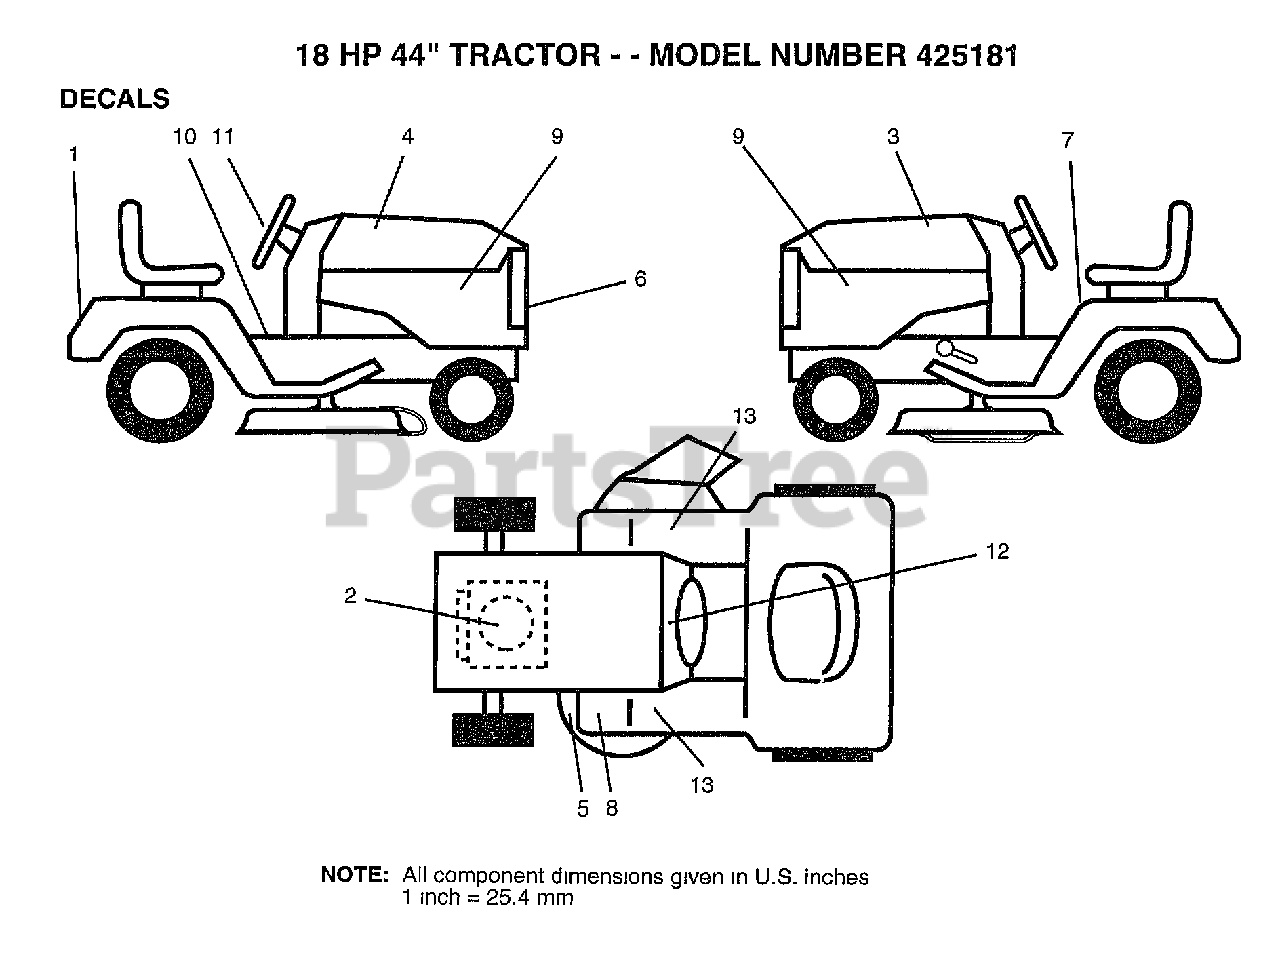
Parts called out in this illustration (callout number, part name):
2	"DECAL,HP ENGINE"
3	DECAL HOOD LH
5	"DECAL.V.BELT.44"""
6	DECAL.GRILL.YARDP
7	DECAL
9	DECAL.PANEL.SIDE
10	DECAL BRAK PARK
11	DECAL.INS.WHL.STG
12	DECAL.DASH.INST.
13	FOOTREST PAD
